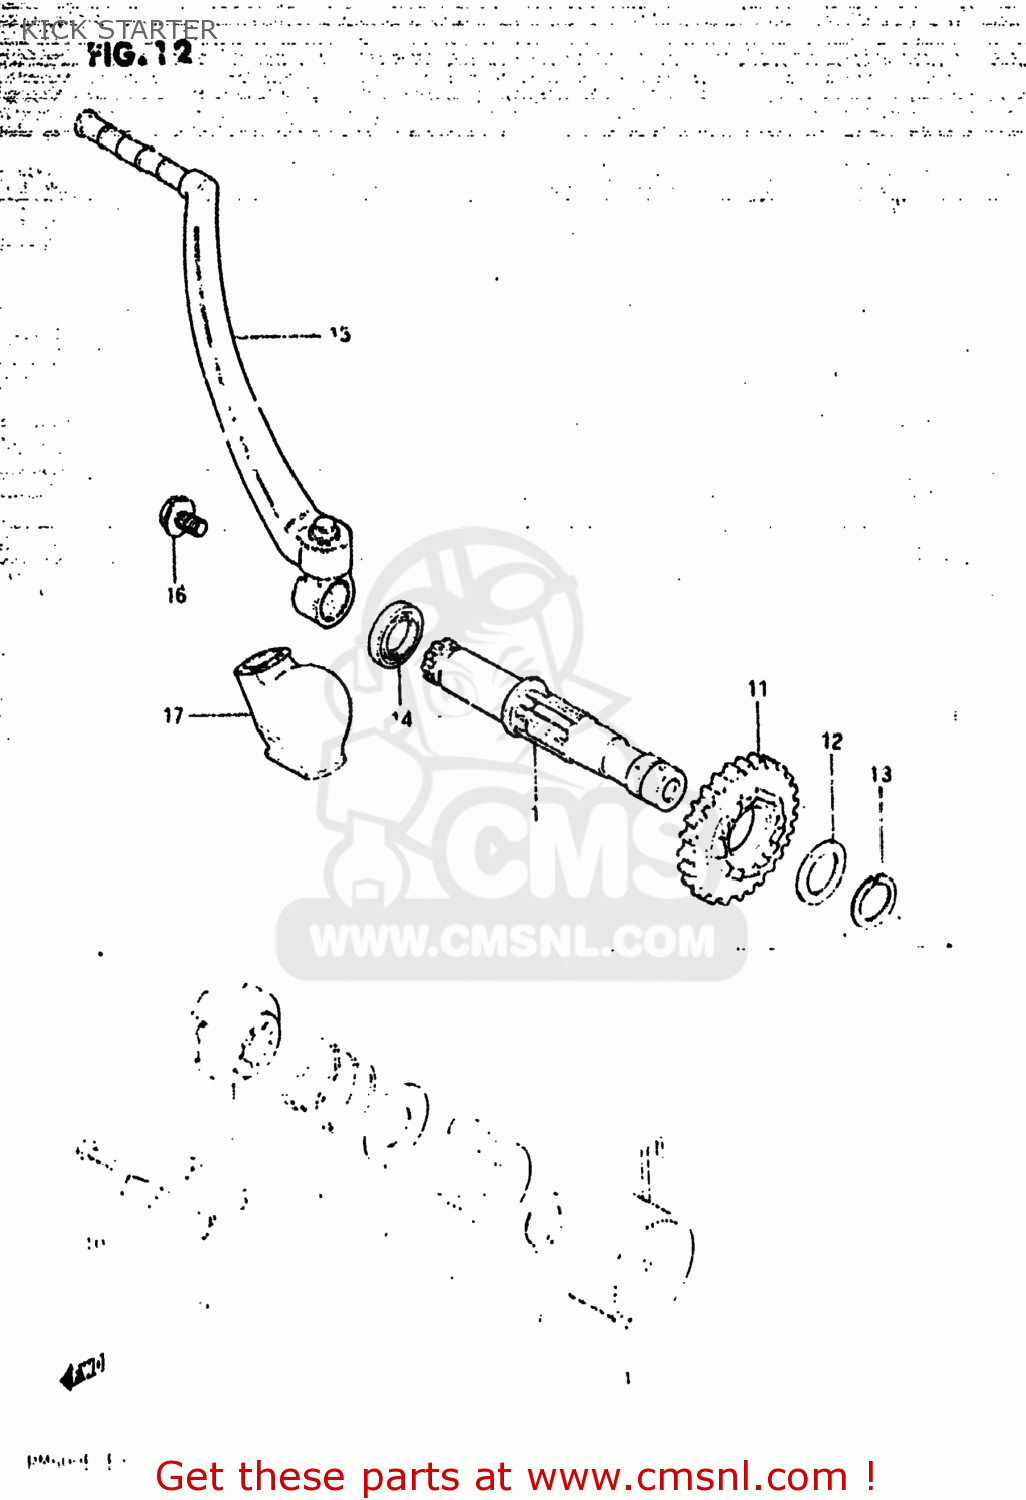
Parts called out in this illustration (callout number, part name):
1	SHAFT,KICK STARTER
2	GUIDE,KICK STARTER SFT SPRING
3	CIRCLIP
4	SPRING
5	STARTER,KICK
6	SPRING
7	WASHER
8	GUIDE,KICK STARTER
9	STOPPER,KICK STARTER
10	BOLT(8X20)
11	GEAR,KICK STARTER DRIVE
12	SHIM
13	CIRCLIP
14	SEAL,OIL(20X27X5)
15	LEVER ASSEMBLY,KICK STARTER
16	BOLT(8X14)
17	COVER,KICK STARTER LEVER JOINT
